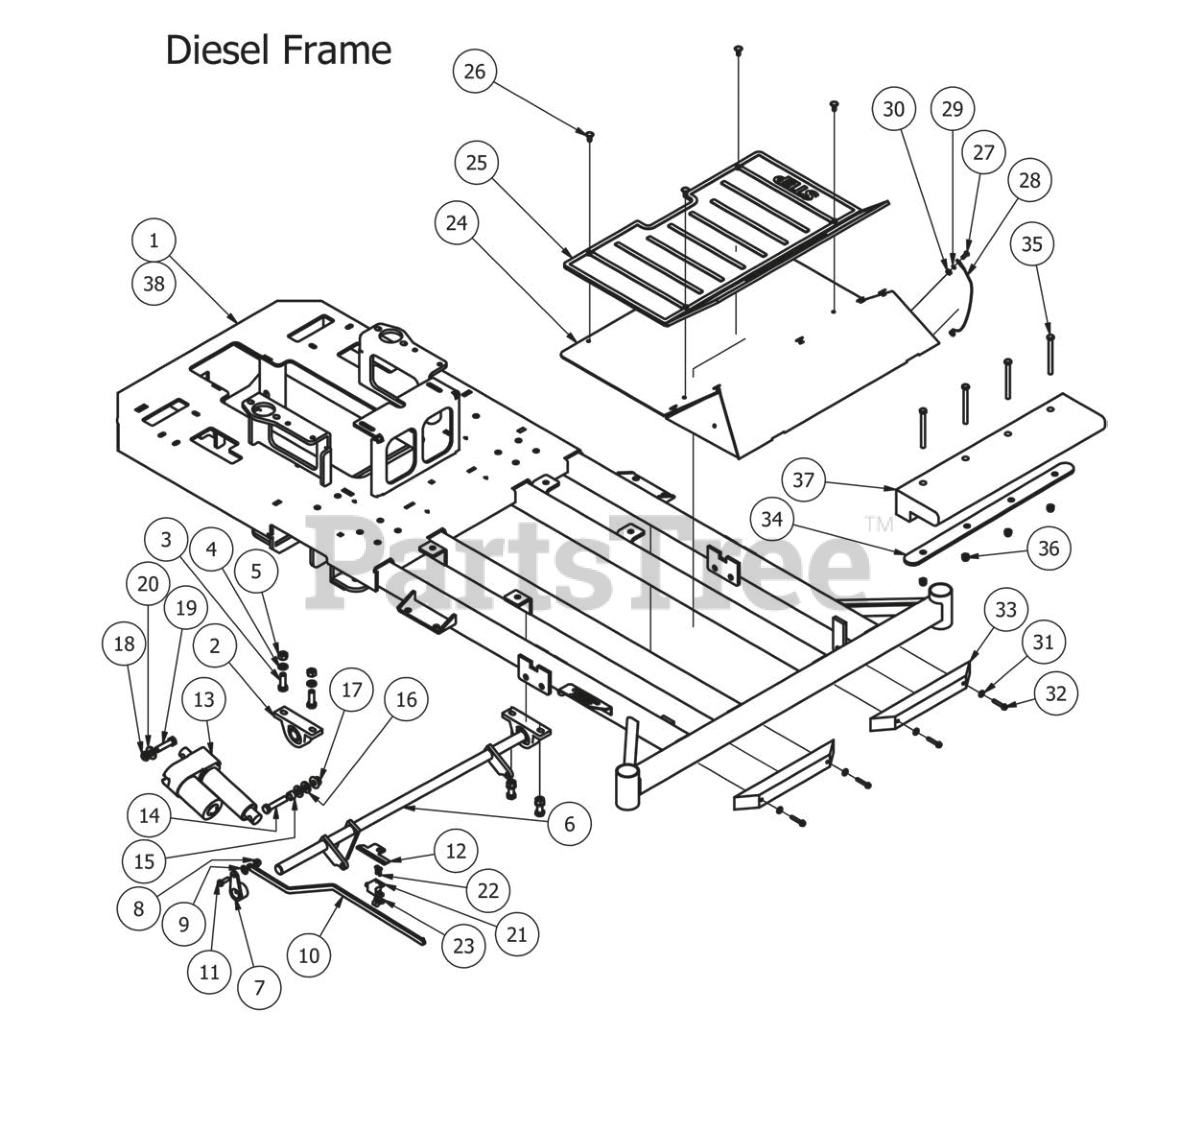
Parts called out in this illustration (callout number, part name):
1	Diesel 4cyl 72" Frame
2	pillow block 2bolt sealmaster
3	1/2" x 1 1/2" Hex Bolt
4	1/2" Lock Washer
5	1/2" Hex Nut
6	Actuator Bar
7	Height Indicator Lever
8	5/16" Flange Nut
9	.360 ID Plastic Washer
10	Height Indicator Bar
11	5/16" x 1" Bolt
12	Deck Stop Bracket 2008
14	1/2" x 2 1/2" Hex Bolt
15	1/2 x 1/2 Spacer
16	.505 Nylon Spacer
17	1/2-13 Nylon Flange Nut-Orange
18	1/2" Nylcock Nut (1/2 Jam)
19	1/2" x 2" Hex Bolt
20	1/2" Washer (Grade 8)
21	Deck Stop Switch
22	1024 x 1" Allenhead Bolt
23	M6x1.0x20MM 8.8 Hex Bolts Zinc
24	Floor Panel
25	AOS Floor Mat
26	Ratchet Fastener-Floorboard
27	1/4" x 5/8" Buttonhead Bolt
28	Floor board Cable W/ Swivel Ends
29	1/4" Lock Washer
30	1/4" Hex Nut
31	1/4" Flat Washer
32	1/4" x 1 1/2" Self Tapping Screw
33	14" Rubber Bumper
34	Diesel Weight Bar Bracket
35	3/8" x 4 1/2" Bolt
36	3/8 Nylock Nut
37	58lb Diesel Weight
38	Diesel 4cyl 61" Frame Suspension
